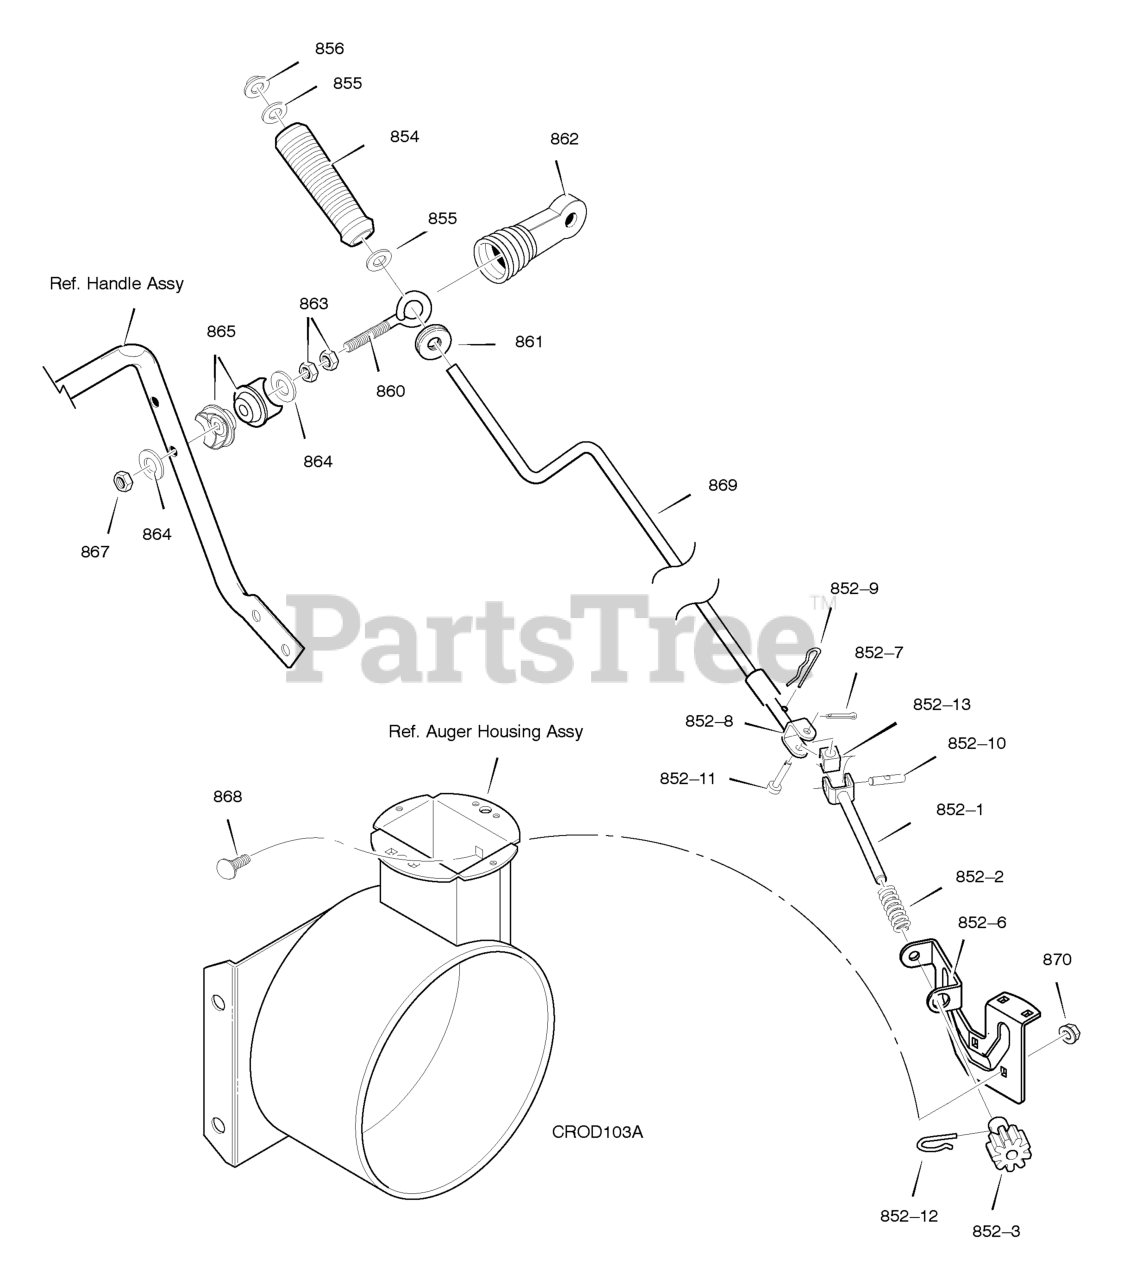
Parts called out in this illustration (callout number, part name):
852-1	ASSEMBLY, YOKE & ROD
852-2	SPRING, COMPRESSION
852-3	GEAR, CHUTE ROTATION 9T
852-6	BRACKET, GEAR MOUNT
852-7	PIN, COTTER
852-8	ASSEMBLY, YOKE ADAPTER YZ
852-9	PIN, HAIR
852-10	PIN, UNIVERSAL JOINT
852-11	PIN, CLEVIS
852-12	PIN, HAIR
852-13	HOUSING, UNIVERSAL
855	FLATWASHER
856	NUT, PUSH ON 3/8"
860	EYE BOLT 3/8-16X6.50
861	GROMMET, EYE BOLT
862	BOOT, EYE BOLT
863	NUT, 3/8-16 HEXJAM
864	FLATWASHER .406X.81X.066
865	ADAPTER, BOOT (2 REQUIRED)
867	NUT, 3/8-16 HEXNYL
868	BOLT, CARRIAGE 1/4-20 X 1.00
869	CRANK, ASSY CHUTE
870	NUT, 1/4-20 NYLOCK
